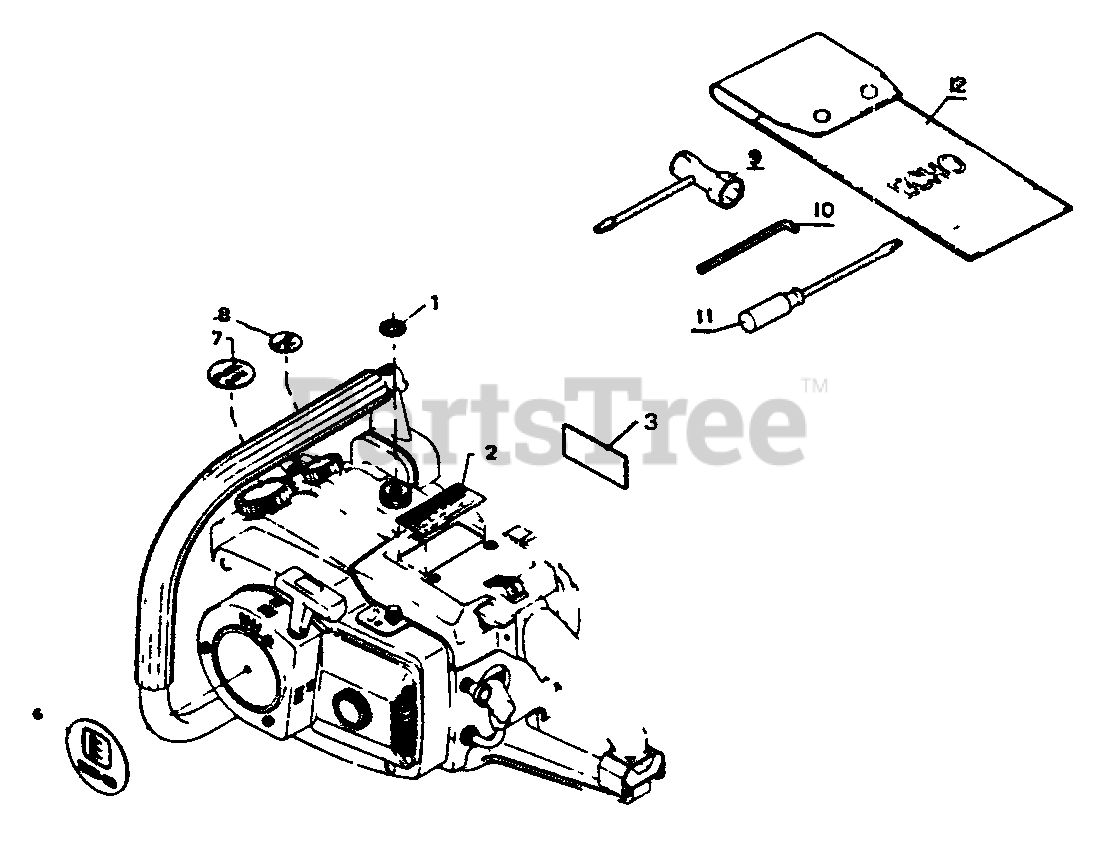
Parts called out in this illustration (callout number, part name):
1	LABEL, CAUTION
2	LABEL - CAUTION
3	LABEL - ECHO
6	LABEL - ECHO
7	LABEL - FUEL MIX
8	LABEL - CHAIN OIL
9	T-WRENCH 13×19×180
10	WRENCH, ALLEN 4 MM
11	SCREWDRIVER, SLOTTED
12	BAG, TOOL
